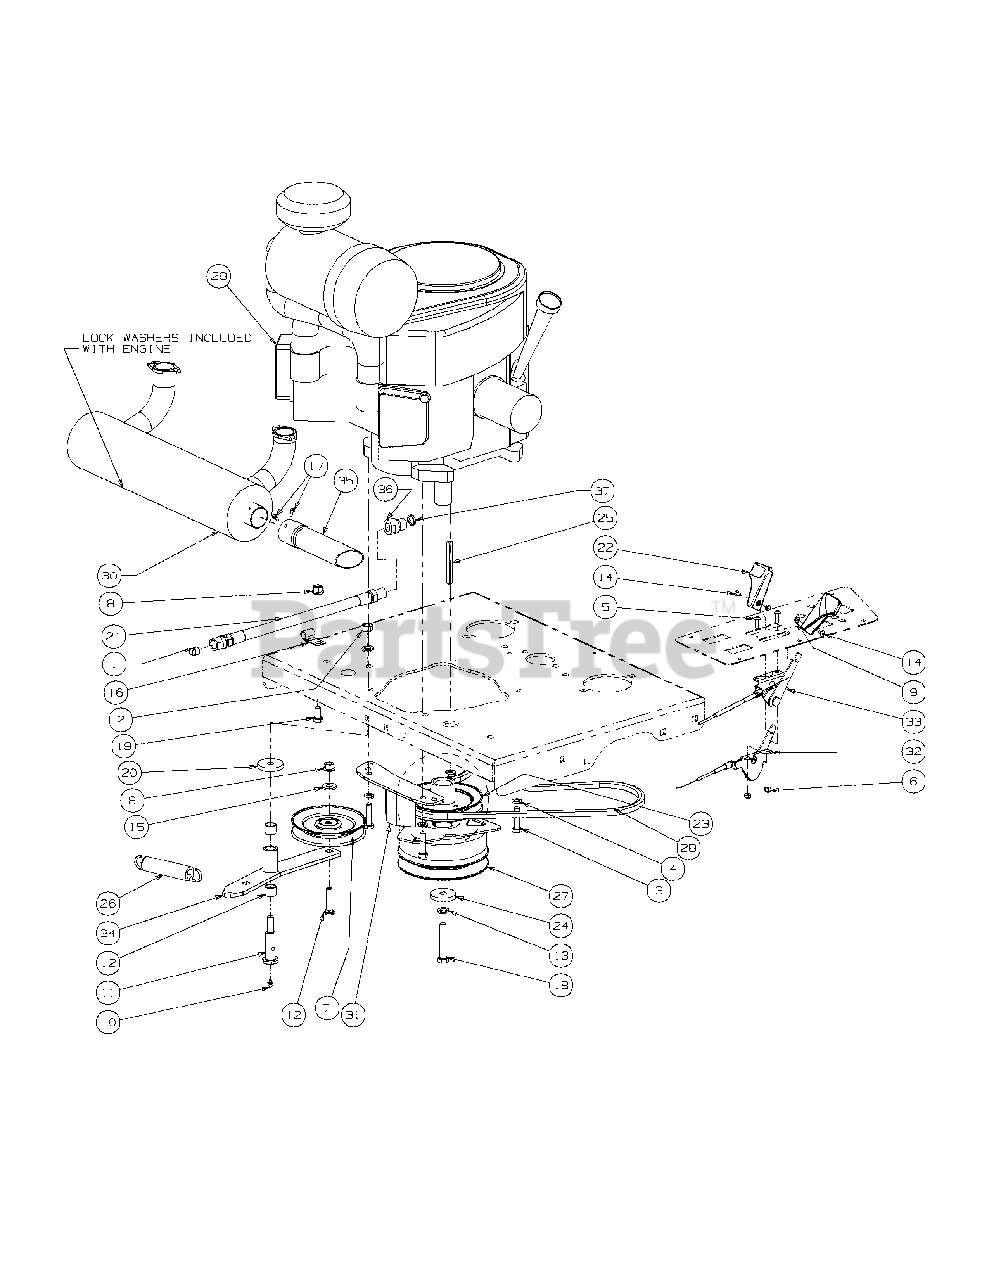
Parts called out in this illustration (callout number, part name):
1	Pipe Plug, 3/8 NPT
2	Hex Nut, 7/16-14
3	HHCS, 3/8-16, 1-1/2
4	Lock Washer, 3/8
5	Round Hd. Machine Screw, 10-32 x 3/4
6	Lock Nut, Nylon Insert, 10-32
7	Idler Pulley
8	Flange Lock, Hex Nut, 3/8-16
9	Nut Washer, W/Star, 8-32
10	Grease Fitting, 1/4-28 x 3/16
11	Shoulder Screw, 7/16-14
12	Hex Carriage Screw, 3/8-16, 1.75
13	Lock Washer, 7/16
14	Machine Screw, 8-32, .375
15	Flat Washer, .406 ID, 1.0 OD, .105
16	Clip, Heat Shield Cable
17	Screw, #8-32 x 0.375
18	Capscrew, 7/16-20 x 2.50
19	Hex Cap Screw, 3/8-16, .750
20	Flat Washer, 7/16 ID x 1.75 OD x .25
21	Oil Drain Hose
22	Control Throttle Knob
23	Pump Drive Pulley
24	Flat Washer, 7/16 ID x 1.75 OD x .25
25	Key, 1/4 x 1/4 x 3
26	Extension Spring, .98 OD x 5.00
27	Clutch Brake, 1.125 ID
28	Belt, AA, 56.45
29	Engine, 37HP Kawasaki
30	Muffler, Kawasaki
31	Retainer Clutch Assembly
32	Throttle, Control Cable
33	Choke, Control Cable
34	Engine Idler Arm includes:
35	Muffler Accessory Exhaust Tube
36	Oil Drain Adapter
37	O-Ring Fitting
